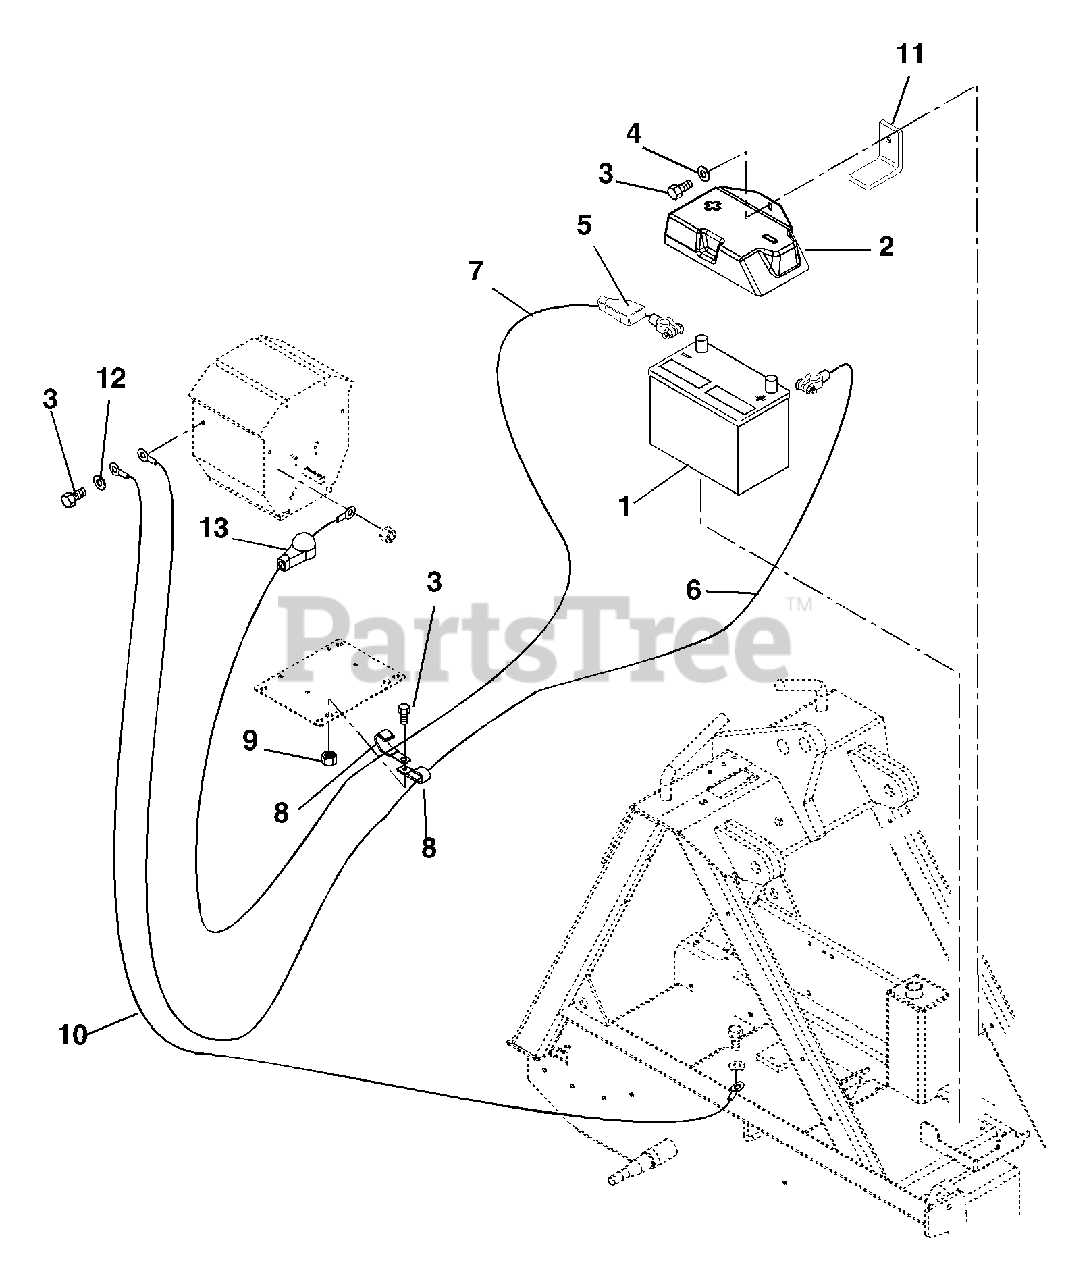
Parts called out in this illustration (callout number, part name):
2	Cover-Battery
3	Bolt-Hex M8 x 1.25 x 16
4	Washer-Flat-Steel .344 x .688 x .065
5	Cover,Battery Terminal
6	Cable-Battery Positive
7	Cable-Battery Negative
8	J-Clamp
9	Nut-Locking-Nylon M8-1.25
10	Wire-Ground
11	Bracket, Battery Holddown
12	Washer-Locking .31 x .078 Regular
13	Battery Terminal Boot, Red
